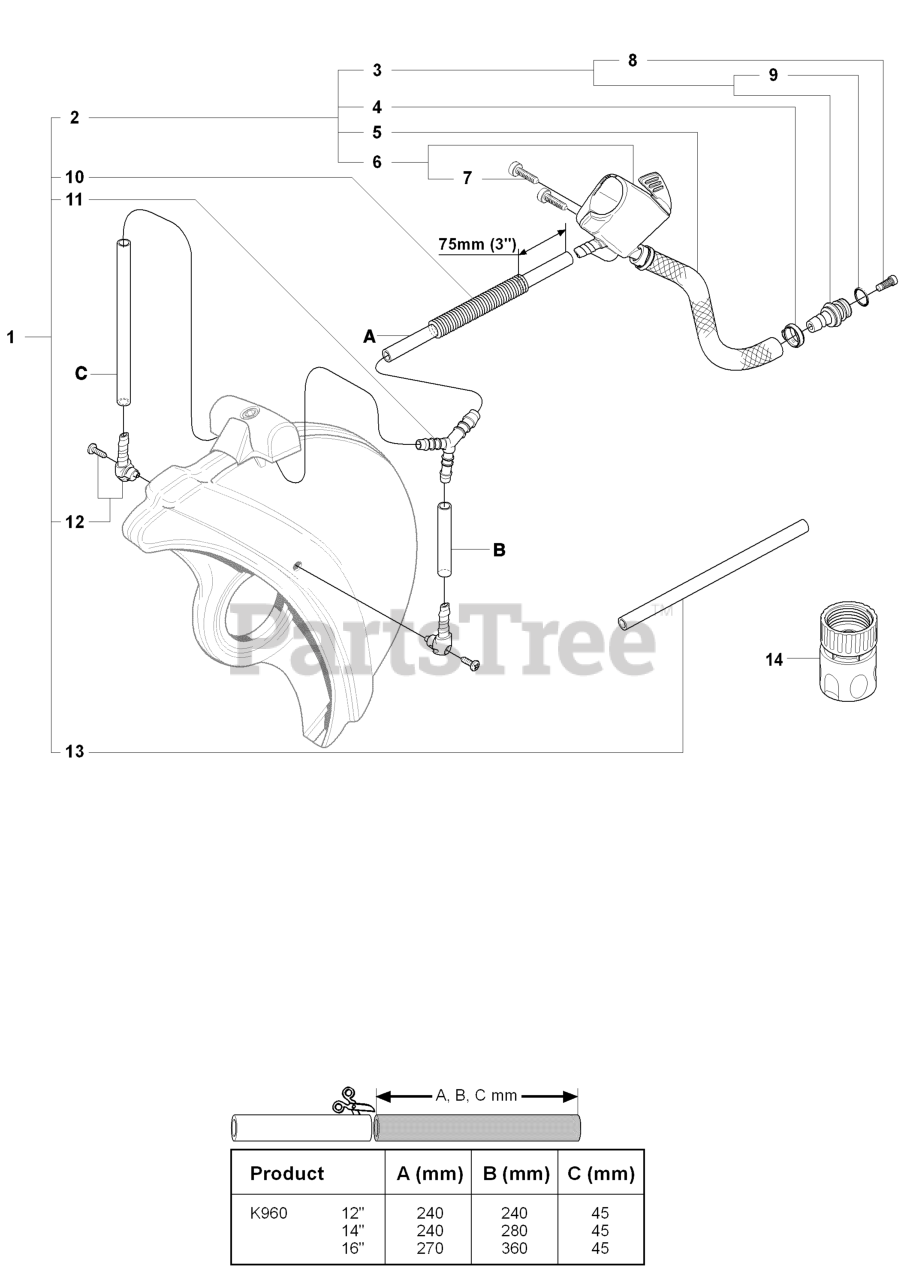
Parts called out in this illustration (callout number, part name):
1	WATER HOSE KIT
2	RP HOSE
3	NIPPLE
4	RP CLAMP
5	%HOSE
6	VALVE ASSY
8	FILTER
9	RP O-RING
10	SPRING
13	RP HOSE 800MM
14	FEMALE QUICK COUPLER
